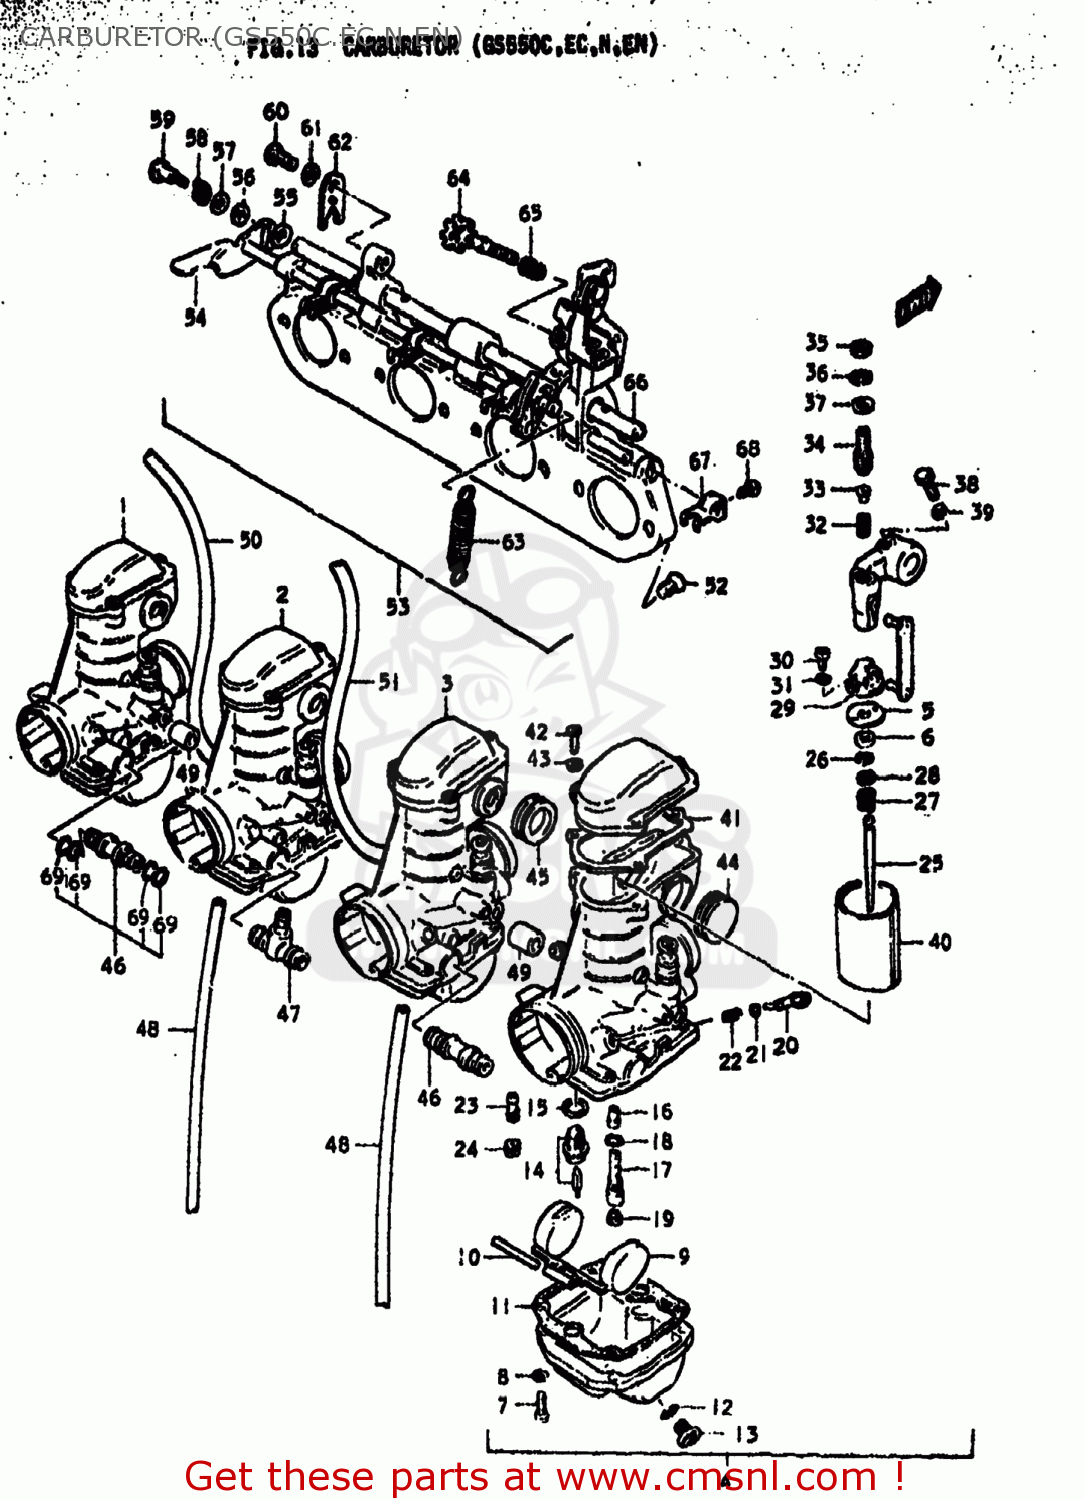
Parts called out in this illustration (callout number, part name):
1	CARBURETOR ASSEMBLY
2	CARBURETOR ASSEMBLY
3	CARBURETOR ASSEMBLY
4	CARBURETOR ASSEMBLY
5	PLATE,THROTTLE VALVE
6	RING
7	SCREW
8	LOCK WASHER
9	FLOAT
10	PIN,FLOAT
11	GASKET,FLOAT CHAMBER (NAS)
12	O RING
13	SCREW
14	VALVE ASSEMBLY,NEEDLE
15	GASKET,VALVE SEAT (NAS)
16	JET,NEEDLE
17	PIPE,BLEEDER
18	O RING
19	JET,MAIN
20	SCREW,PILOT AIR
21	O RING
22	SPRING
23	JET,PILOT(15)
24	JET,AIR(50)
25	NEEDLE JET
26	CLIP
27	SPRING
28	WASHER,JET NEEDLE
29	CONNECTOR
30	SCREW
31	LOCK WASHER
32	SPRING
33	PIN,CARBURETOR
34	SCREW
35	NUT
36	LOCK WASHER
37	WASHER
38	BOLT
39	LOCK WASHER
40	VALVE,THROTTLE
41	GASKET (NAS)
42	SCREW
43	LOCK WASHER
44	PIPE,DELIVERY
45	SEAL
46	NIPPLE
47	NIPPLE
48	HOSE
49	HOSE
50	HOSE
51	HOSE 4.5X8X390
52	SCREW
53	CARBURETOR ASSEMBLY
54	SHAFT,STARTER
55	WASHER,STARTER SHAFT
56	WASHER
57	WASHER,STARTER SHAFT
58	SPRING
59	SCREW,STARTER LEVER
60	SCREW
61	LOCK WASHER
62	GASKET
63	SPRING,THROTTLE VALVE
64	ADJUSTER
65	SPRING,THROTTLE SCREW
66	SHAFT ASSEMBLY
67	LEVER, STARTER
68	SCREW
69	O-RING
